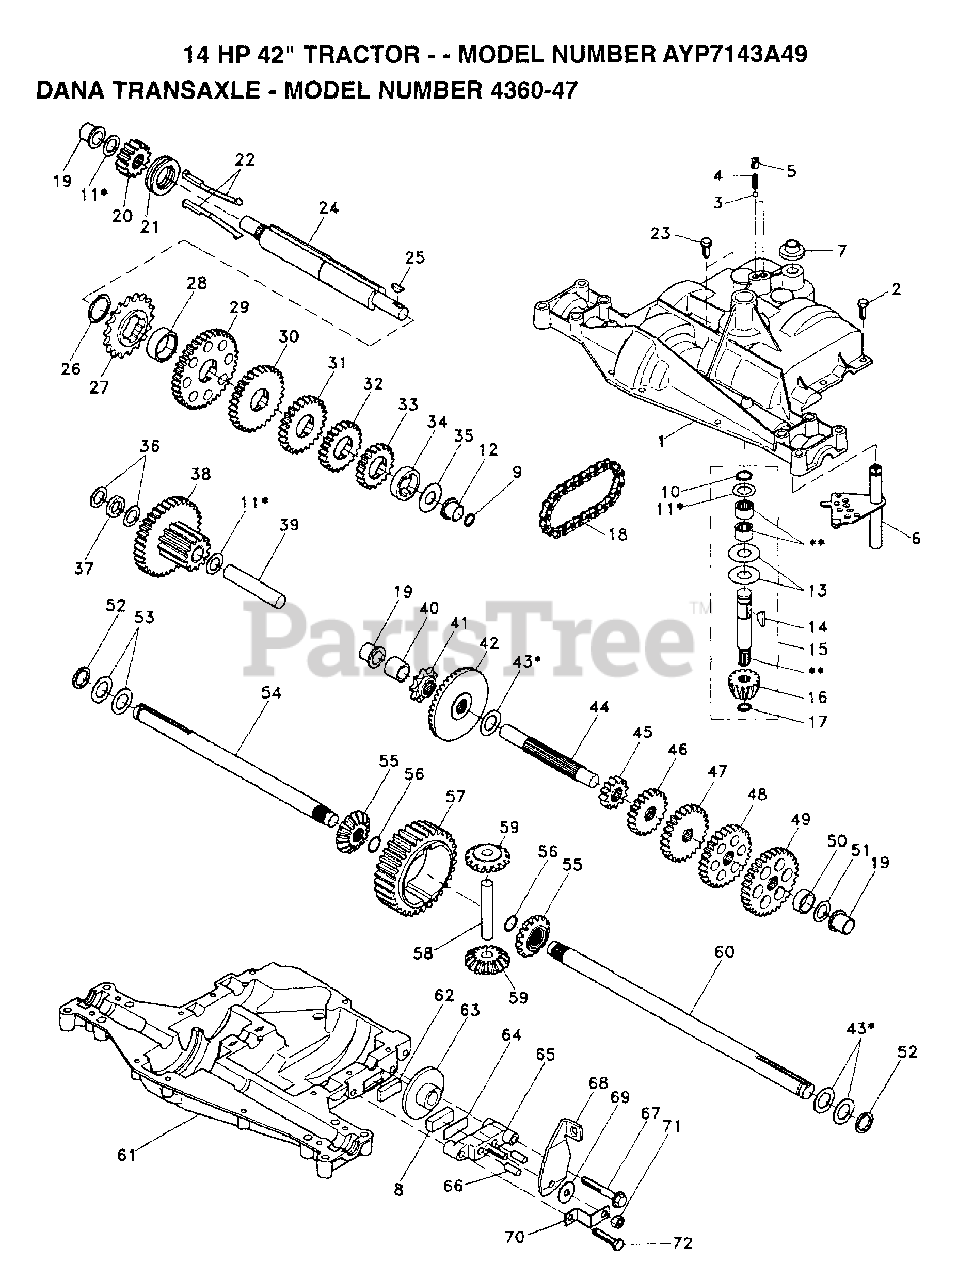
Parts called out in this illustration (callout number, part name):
1	HOUSING UPPER
3	BALL, DETENT
4	SPRING, DETENT
5	SCREW, SET
6	SHIFTER ASSEMBLY
7	BOOT, SHIFTER
8	PUCK, FRICTION
9	SQUARE RING
10	RING RETAINING
11	ASSY, KIT, SHIM .625 SHAFT
12	BEARING FL
13	WASHER, PLAIN .632 X 1.38 X .046
14	KEY WOODRUFF #9
15	ASSEMBLY, KIT, INPUT SHAFT
16	PINION, BEVEL, 14 TEETH
17	RING, RETAINING
18	CHAIN, 24 PITCHES
19	BEARING, FLANGE
21	COLLAR, CLUTCH
22	ASSEMBLY, KIT, CLUTCH KEYS
23	SCREW TAPPING WITH SEALER
24	SHAFT INTERMEDIATE
25	KEY, WOODRUFF, #61
26	RING, RETAINING
27	SPROCKET, 18 TEETH
29	GEAR, SPUR, 37 TEETH
30	GEAR, SPUR, 30 TEETH
31	GEAR, SPUR, 25 TEETH
32	GEAR, SPUR, 22 TEETH
33	GEAR, SPUR, 19 TEETH
35	WASHER, PLAIN .640 X 1.37 X .061
36	WASHER, PLAIN .632 X 1.00 X .026
37	SPACER .630 X 1.00 X .169
38	ASSY GEAR COMB 12&35 TEETH
39	SHAFT, IDLER
40	SPACER .635 X .875 X .755
41	SPROCKET, 9 TEETH
42	GEAR, BEVEL, 42 TEETH
43	ASSY, KIT, SHIM .750 SHAFT
44	SHAFT, DRIVE
45	GEAR, SPUR, 12 TEETH
46	GEAR, SPUR, 20 TEETH
47	GEAR, SPUR, 25 TEETH
48	GEAR, SPUR, 28 TEETH
49	GEAR, SPUR, 31 TEETH
51	WASHER, PLAIN .632 X 1.00 X .060
52	WASHER, NEOPRENE
53	WASHER, PLAIN .758 X 1.25 X .031
54	AXLE LEFT HAND
55	GEAR, MITER, 15 TEETH
56	RING, RETAINING
57	GEAR, SPUR, 22 TEETH
58	SHAFT, CROSS
59	GEAR, MITER, 15 TEETH
60	AXLE, R.H.
61	HOUSING LOWER
62	PUCK, FRICTION
63	DISC, BRAKE
65	JAW, BRAKE
66	PIN, DOWEL
67	SCREW, SELF-TAPPING
68	LEVER ACTUATING
69	WASHER, PLAIN .321 X 1.00 X .055
70	BRACKET, ANTI-ROTATION
71	LOCKNUT 5/16-24
72	SCREW TAPPING
